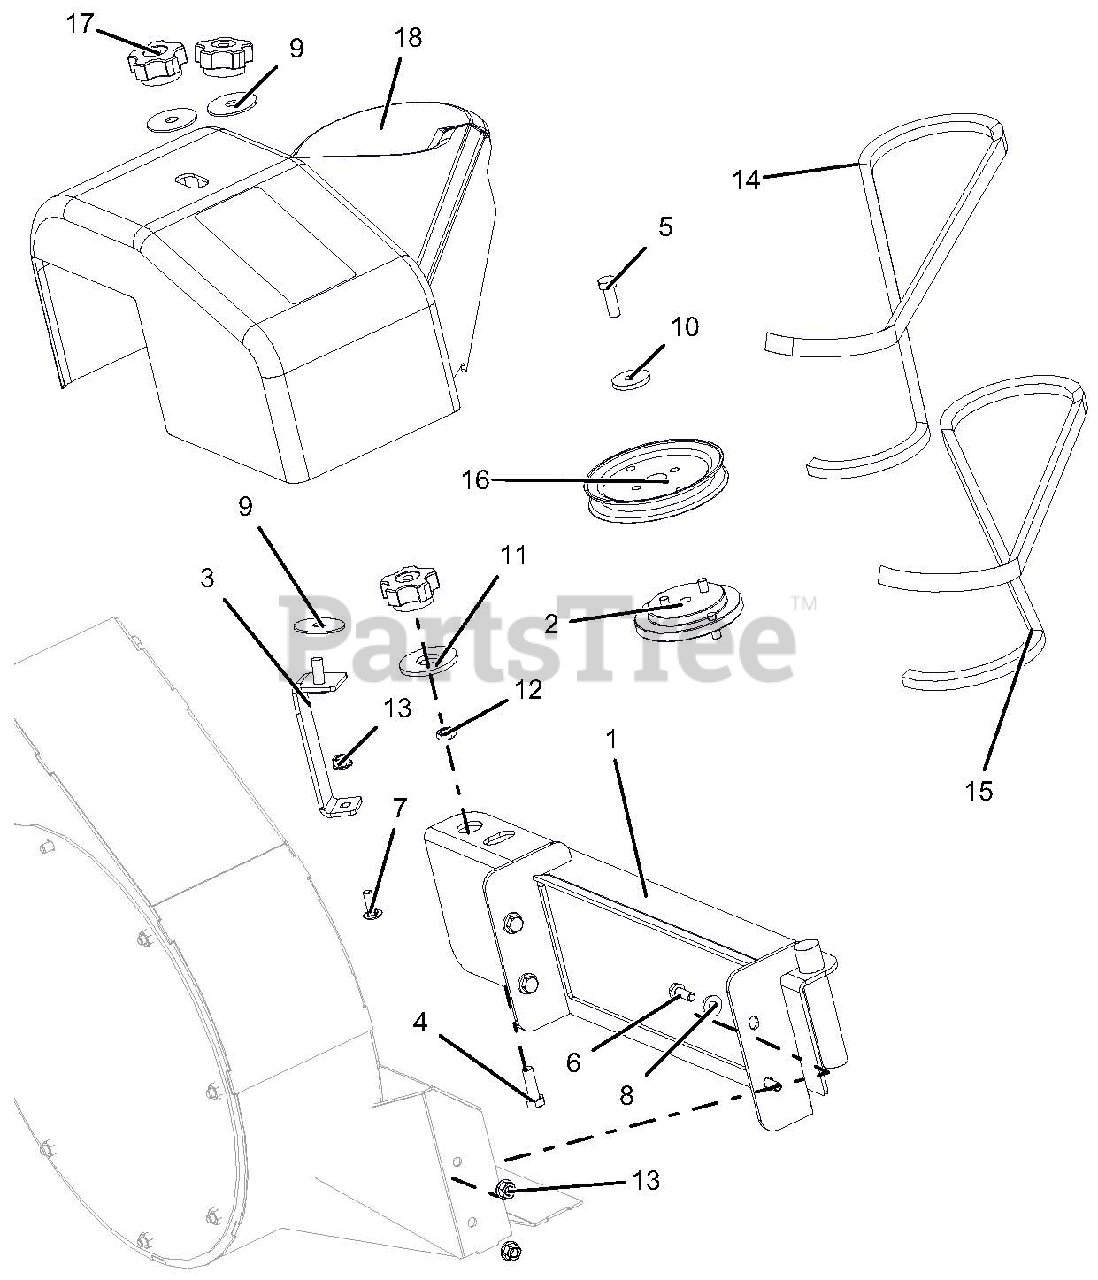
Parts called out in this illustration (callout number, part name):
1	WLDMT, GRASS PUMP MOUNT
2	ASM, BAGGER SHEAVE ADAPTER
3	WLDMT, BAGGER BELT COVER BRKT
4	BLT-HEX .31-18X1.00 GR8 YWZC
5	BLT-HEX .31-18X1.00 GR8 M-EPYZ
6	BLT-HEX .25-20X.75 GR5 YWZC
7	BLT-RDHDSQNK .25-20X.75 G5YZ
8	WSHR-FL-STL.281X.62X.065 YWZC
9	WSHR-FL-STL .380X1.50X.062 YWZ
10	WSHR-FL-STL .344X1.125X.135
11	WSHR-FL-STL.688X1.75X.134 YWZ
12	NUT- JAM .312-18 YWZC
13	NUT-LK-TOP-FLG .25-20 YWZC
14	V-BELT, 4L-RAW EDGE
15	V-BELT, HA-WRAPPED
16	SHEAVE, SPINDLE (4.25 HA )YWZC
17	KNOB-CLAMPING, .312-18 NYLOC
18	COVER, BAGGER BELT -W/DECAL
